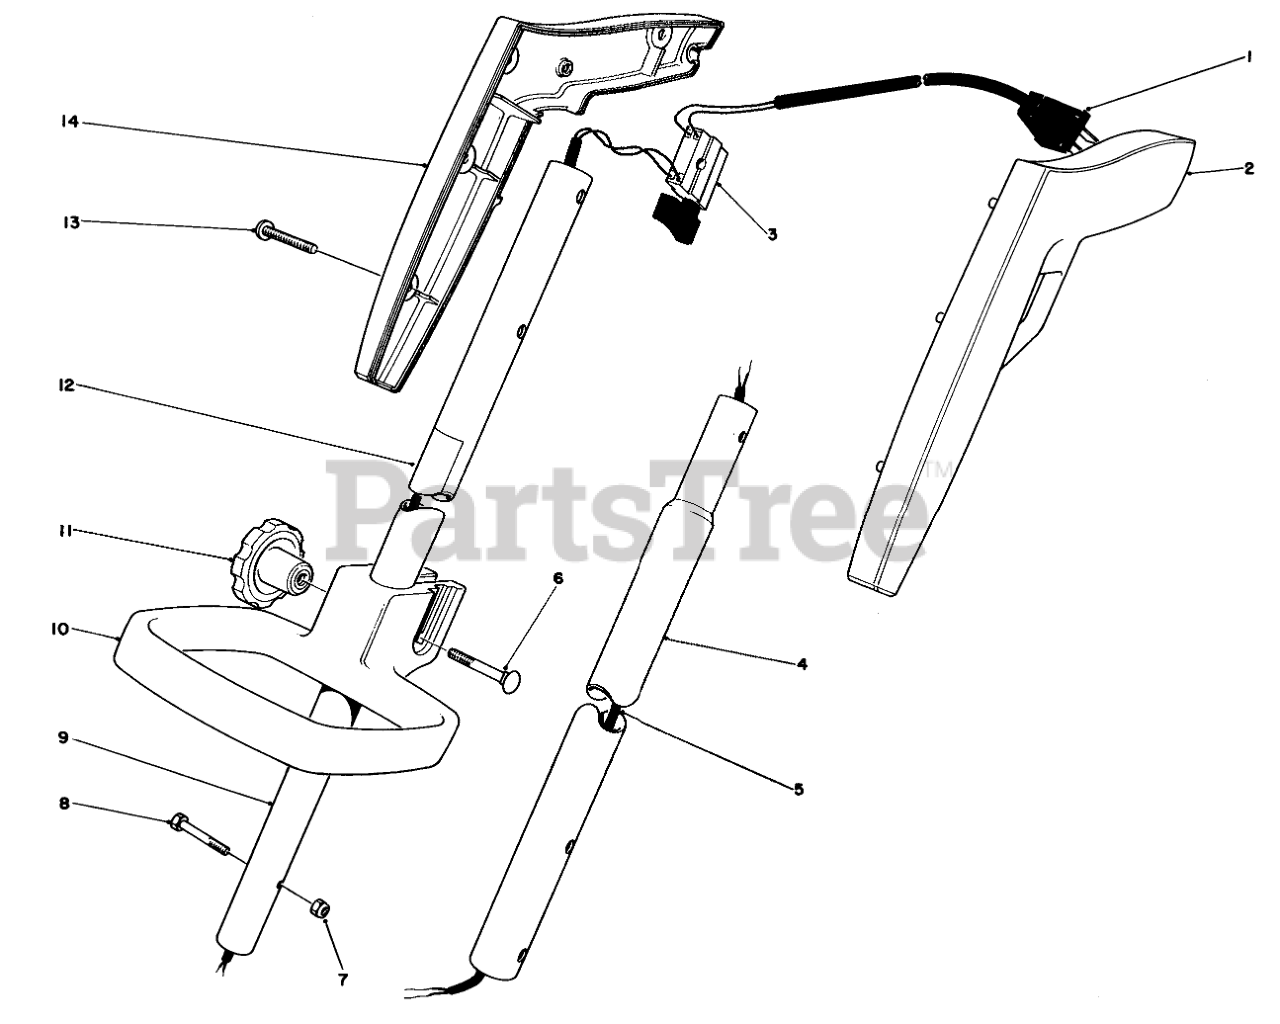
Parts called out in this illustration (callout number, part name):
1	Power Cord
2	Grip L.H.
3	SWITCH SINGLE SPEED
4	Tube-Lower
5	Wiring Harness
6	BOLT-CARR
7	NUT-LOCK, NI
8	HEX HD MACHINE SCREW
9	Tube-Upper
10	ADJUSTABLE HANDLE
12	Decal-Serial (Canada)
13	Screw
14	R.H. GRIP
